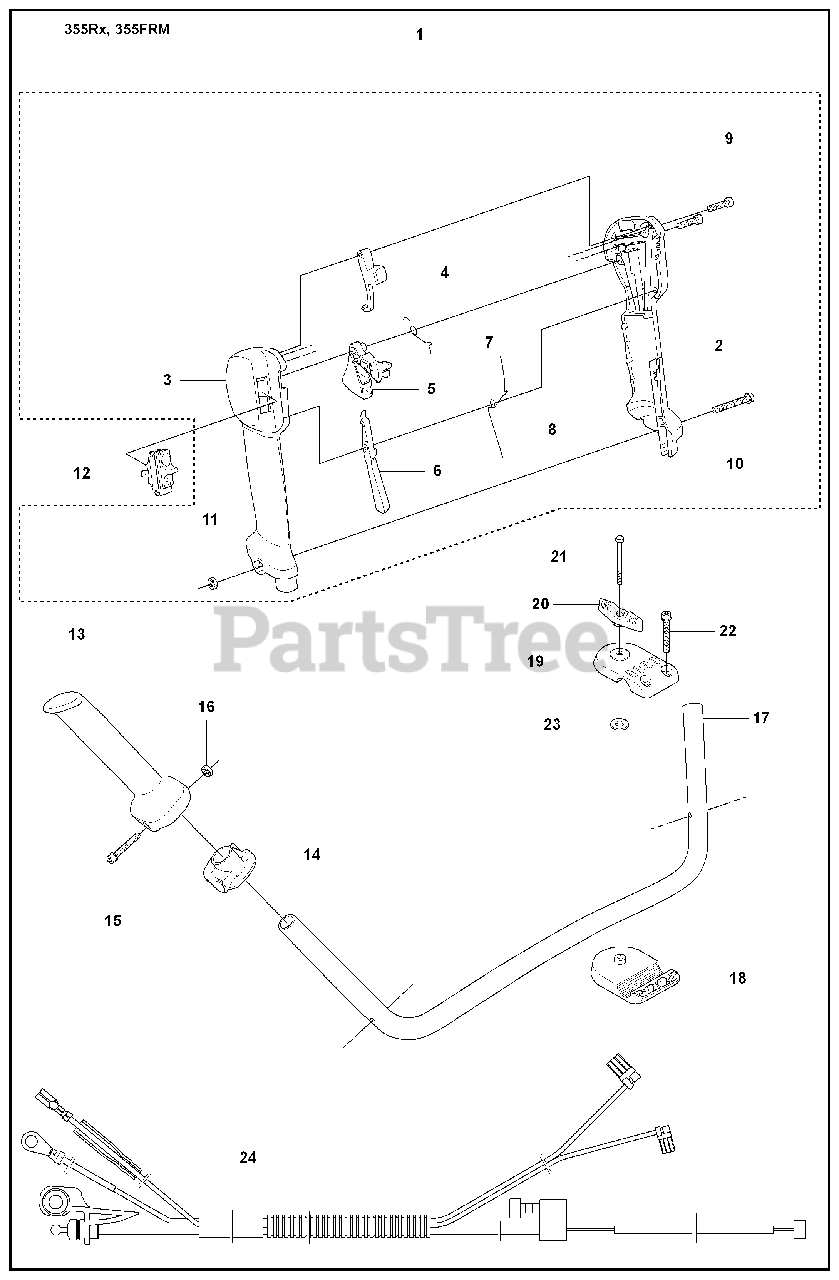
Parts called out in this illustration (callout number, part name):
1	THROTTLE HANDLE ASSY
2	HANDLE HALF RIGHT
3	HANDLE HALF LEFT
4	LOCKOUT STARTER THROTTLE
5	%THROTTLE TRIGGER
6	%THROTTLE LOCK
10	%SCREW
12	STOP BUTTON
16	NUT M6M M5
17	HANDLE
18	HANDLE HOLDER LOWER
19	HANDLE HOLDER UPPER
21	%SCREW
24	WIRING
